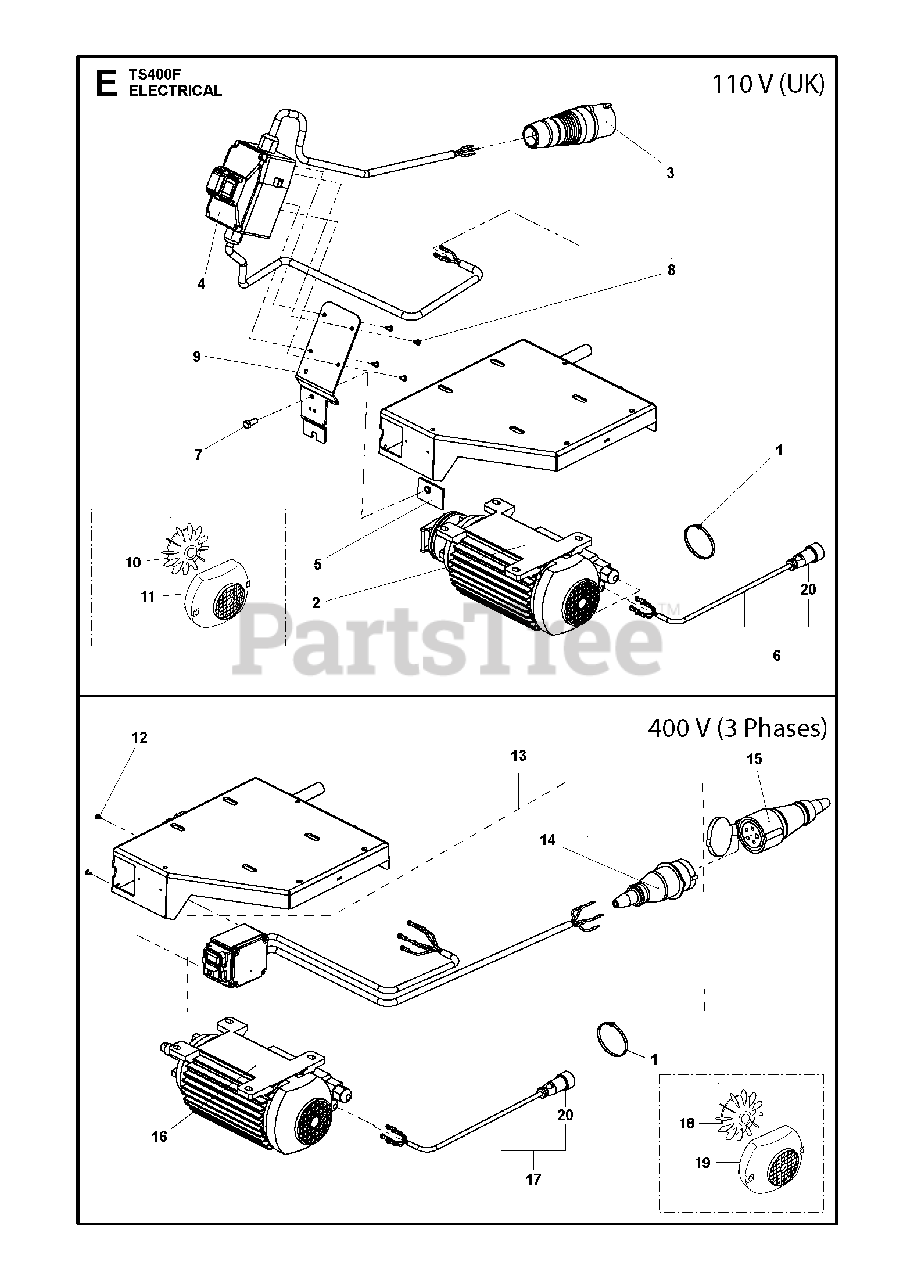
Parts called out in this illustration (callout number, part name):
3	FICHE 2P+T 32A 110V 4H/PRESSE
5	TOLE DE SERRAGETS350F
8	SCREW EHHM
9	SUPPORT TRIPUS 110VTS400F
12	SCREW CRPANT
13	SWITCHCompl. 3 phase 200V/400V
14	FICHE 16A 380V 3P+N+T 6H/AVEC*
15	PROLONG. 3P+N+T 16A 6H/
